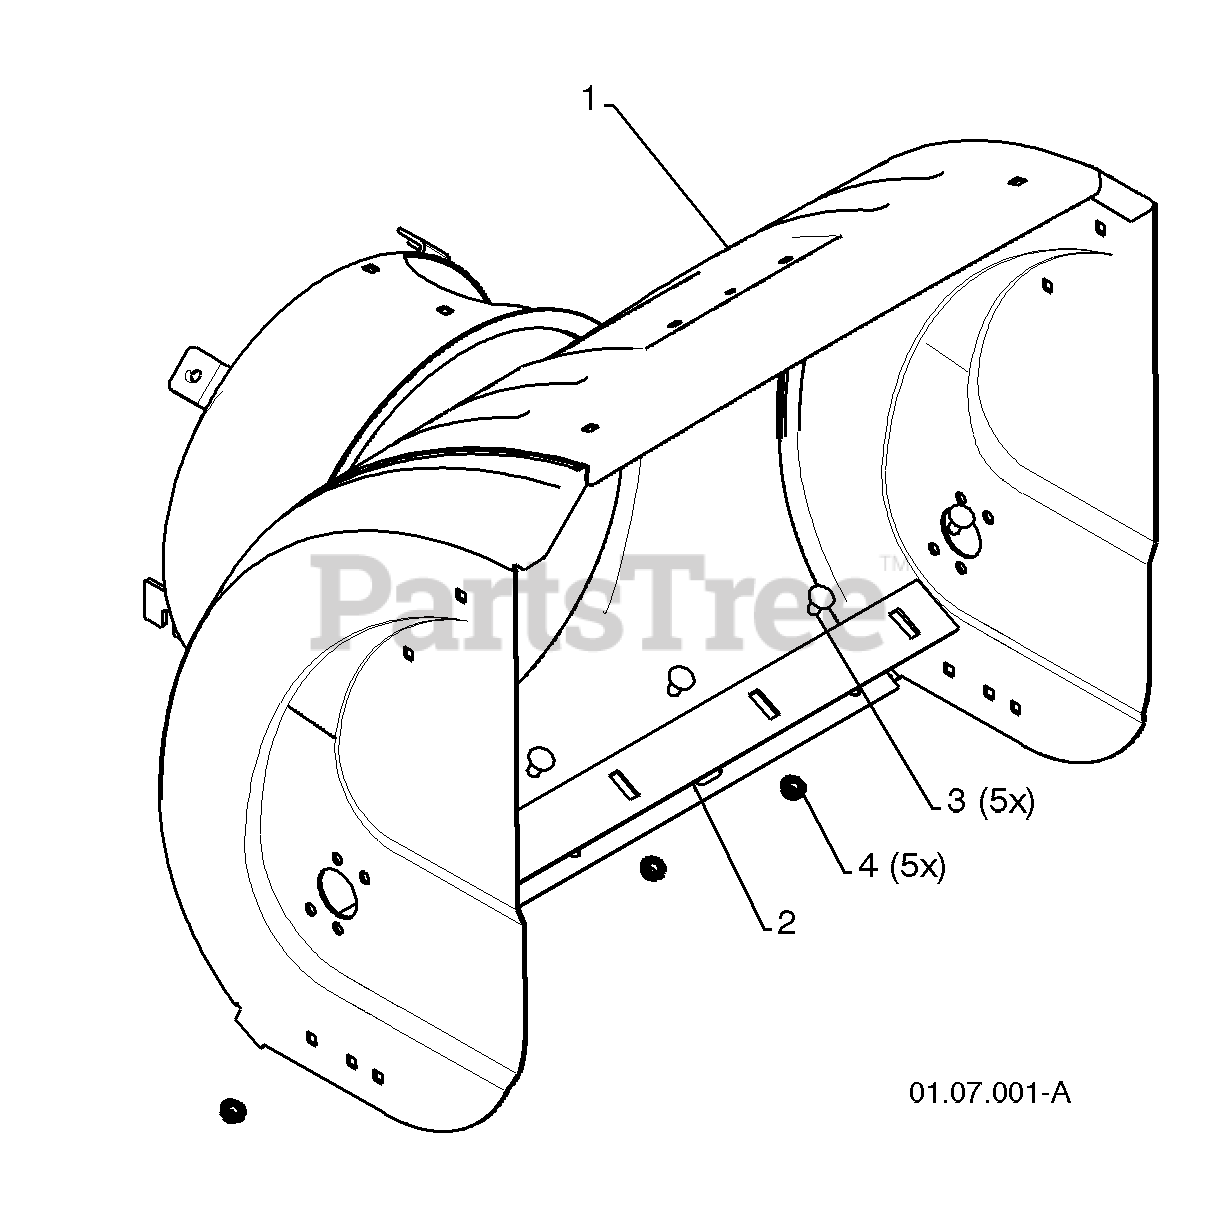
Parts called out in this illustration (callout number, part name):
1	AUGER HOUSING
2	SCRAPPER BAR
3	CARRIAGE BOLT 5/16-18 X .625
4	NUT 5/16-18
